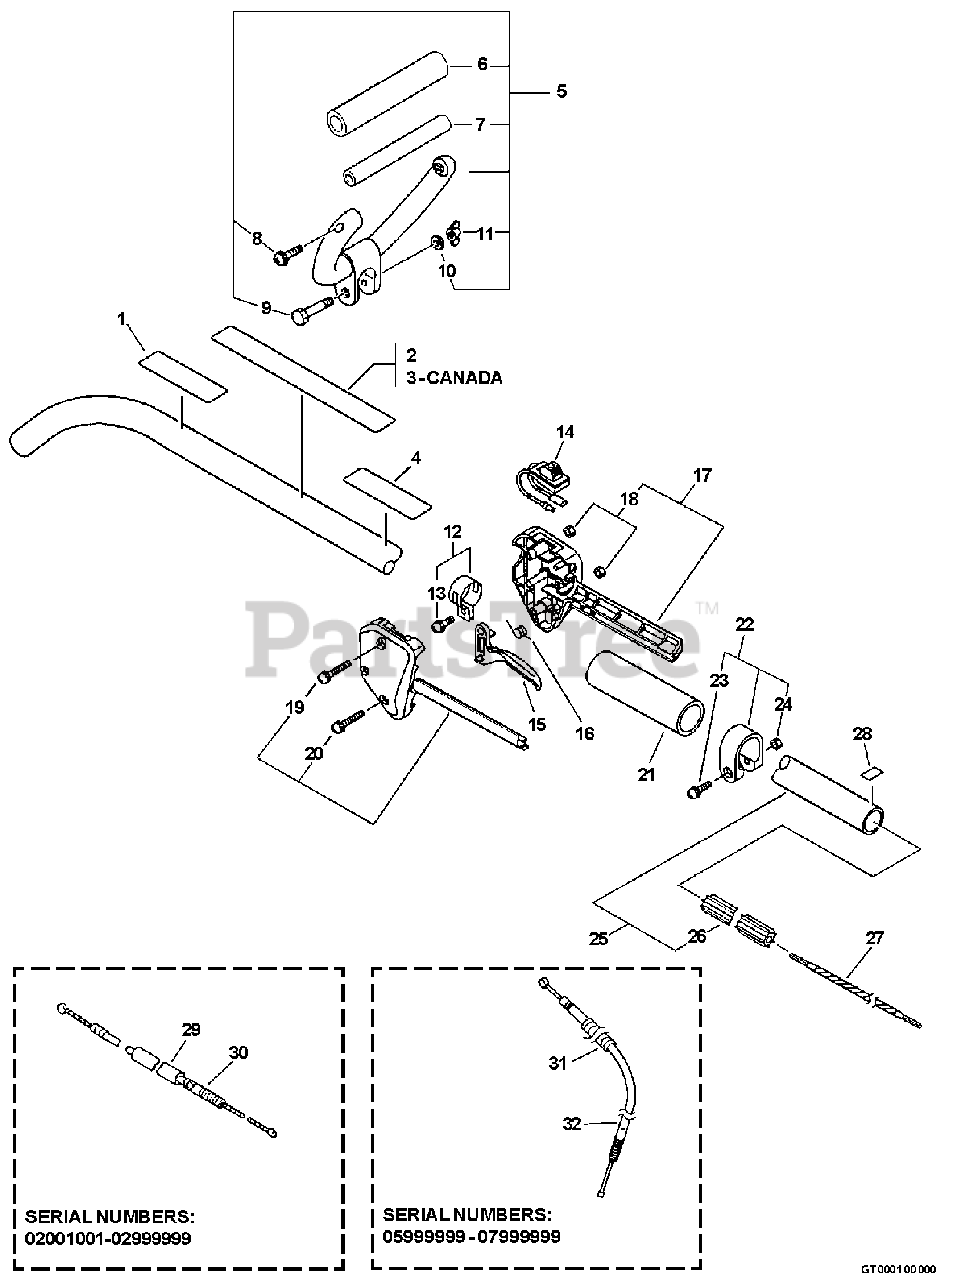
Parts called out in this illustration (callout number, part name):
1	LABEL - CAUTION -- SPANISH
2	LABEL - CAUTION
3	LABEL - CAUTION
4	LABEL - HANDLE LOCATION
5	LOOP HANDLE ASSY
6	GRIP, HANDLE
8	SCREW - 5X30
9	BOLT - 6X40
10	WASHER - 6
11	WINGNUT - 6
12	CLAMP KIT
13	SCREW - 5X14
14	IGNITION SWITCH ASSY
15	TRIGGER, THROTTLE
16	SPRING, TRIGGER
17	CONTROL HANDLE ASSY
19	SCREW - 5X35
20	SCREW - 5X25
21	GRIP, HANDLE - REAR
22	CLAMP KIT
23	SCREW - 5X28
25	MAIN PIPE ASSY
26	LINER - FLEXIBLE
27	DRIVESHAFT - FLEXIBLE
28	LABEL - ALIGNMENT
29	TUBE, PROTECTIVE - CORRUGATED
30	CABLE, THROTTLE
31	TUBE, PROTECTIVE - CORRUGATED
32	CABLE, THROTTLE
